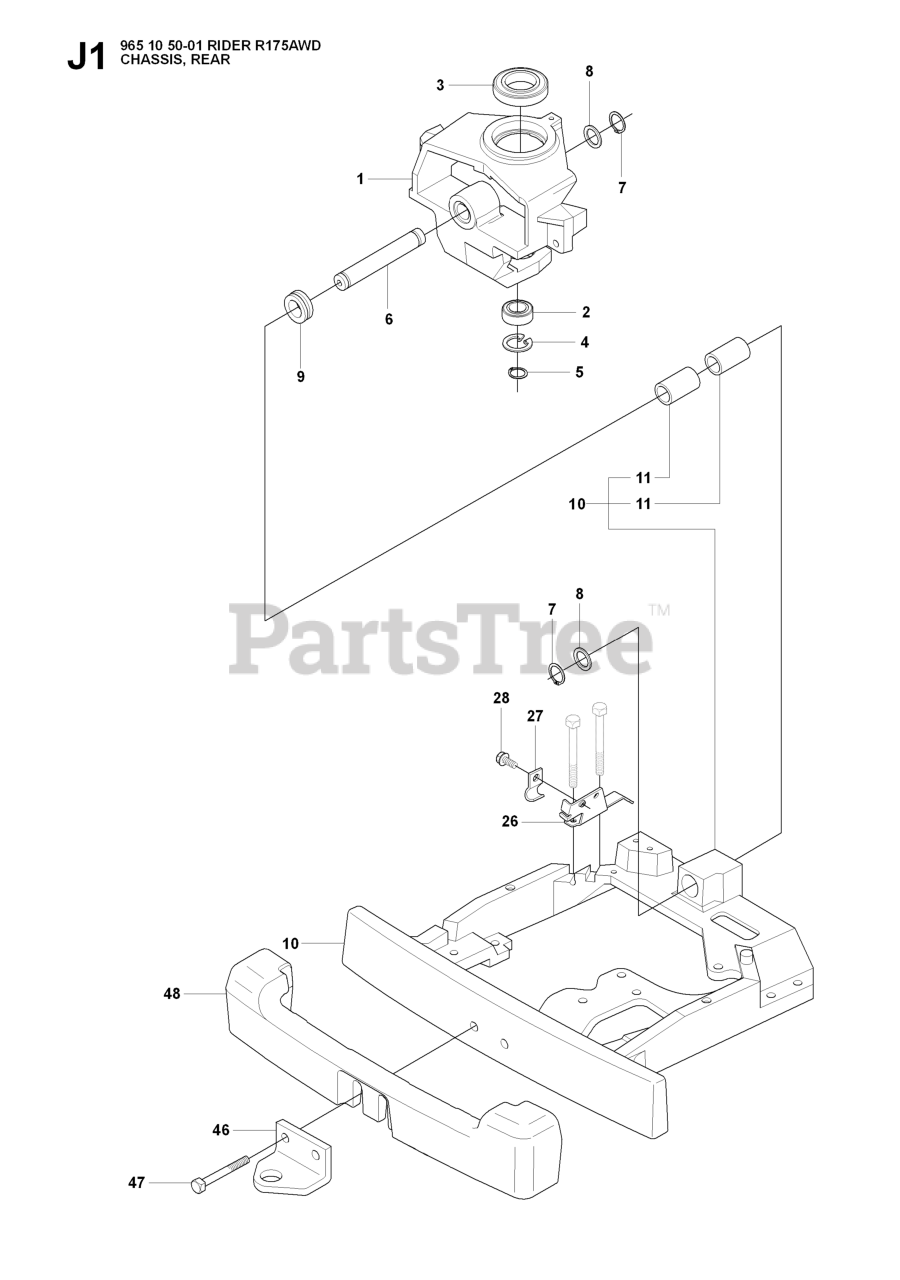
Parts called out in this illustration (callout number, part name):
2	Ball Bearing 6005-2rs
3	BALL BEARING 6010 2RS1
4	CIRCLIP SGH 47
5	RETAINING RING SGA 25
7	RETAINING RING SGA 25
46	REPL BY 725 25 00-71
47	COUNTERWEIGHT
